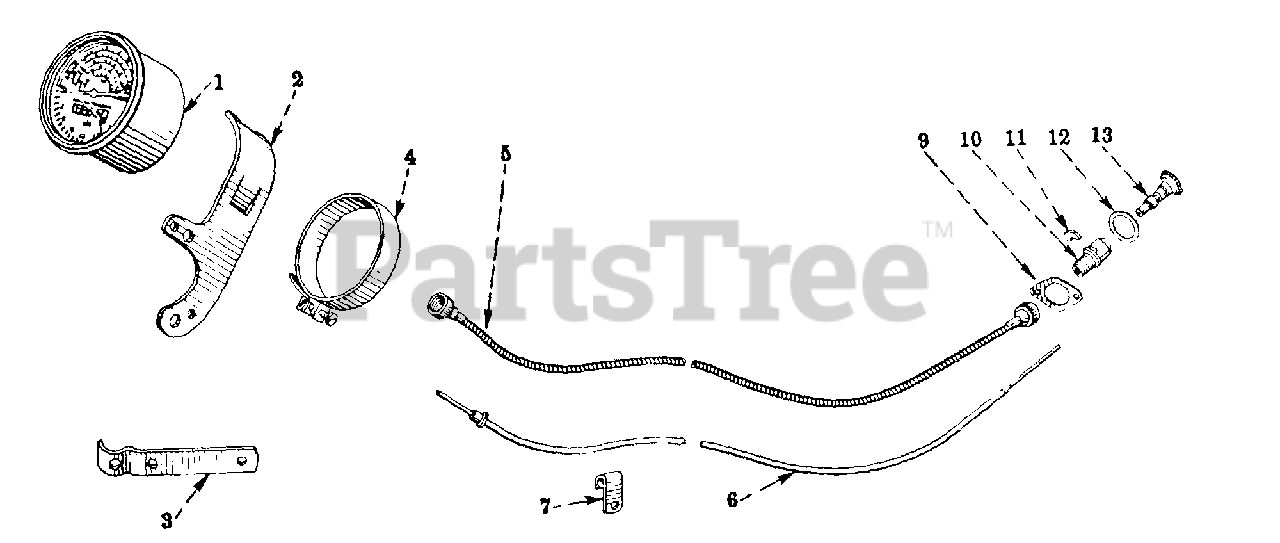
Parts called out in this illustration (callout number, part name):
1	TACHOMETER ASSY
2	BRACKET, TACHOMETER MOUNTING
3	SUPPORT, TACHOMETER MOUNTING BRACKET
4	CLAMP ASSY, TACHOMETER MOUNTING
5	SHAFT, W/CORE,
6	CORE, TACHOMETER FLEXIBLE DRIVE
7	CLIP, TACHOMETER DRIVE CONDUIT
9	PLATE, TACHOMETER CONNECTION HOUSING
10	HOUSING, TACHOMETER CONNECTION
11	RETAINER, TACHOMETER DRIVE GEAR
12	GASKET, TACHOMETER CONNECTION HOUSING
13	GEAR, TACHOMETER DRIVE 32 T
